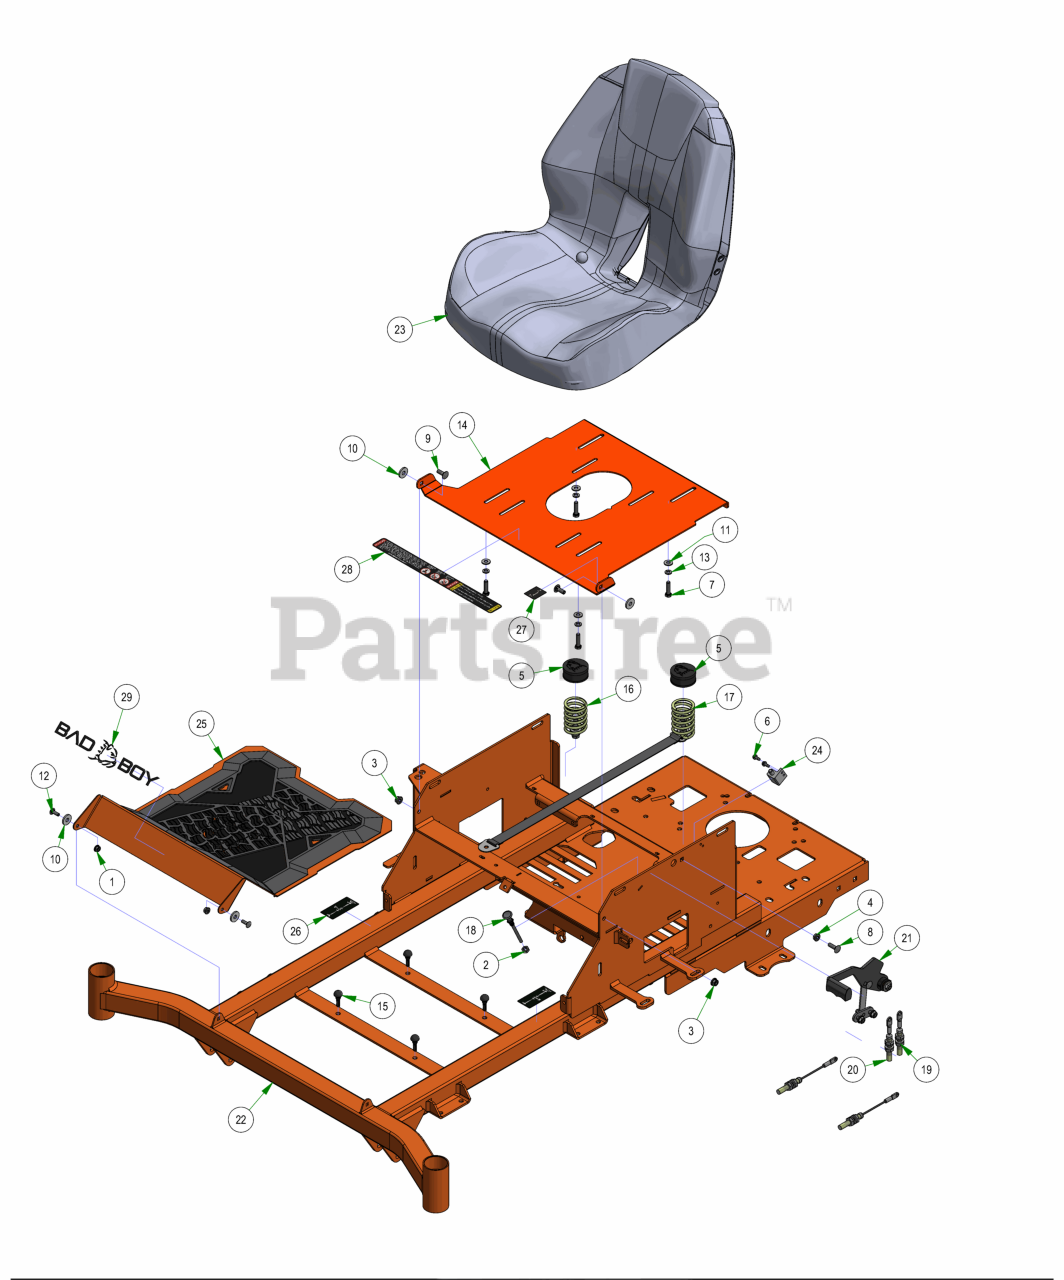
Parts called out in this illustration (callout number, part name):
1	1/4-20 NYL INSERT FLANGE LOCKNUT ZINC
2	3/8-24 HEX NUT ZINC YELLOW
3	5/16-18 NYLON INSERT FLANGE LOCKNUT ZINC
4	5/16-18 HEX SERRATED FLANGE NUT HARD/ZINC
5	Spring Cap Cover
6	12-24 X 1/2 HEX WASHER UNLSOT F TCS ZINC
7	5/16-18 X 1-1/4 HEX C/S (GR.5) ZC
8	5/16-18 X 1 CARRIAGE BOLT (GR.8) ZINC
9	5/16-18 X 7/8 CARRIAGE BOLT ZINC
10	.360 ID X .983 OD X .120 THICK FLAT WASHER NYLON
11	1/4 USS FLAT WASHER (3/4 OD) ZINC
12	1/4-20 X 3/4 CARRIAGE BOLT (GR.5) ZINC
13	5/16 SPLIT LOCKWASHER ZINC
14	2022 Avenger Seat Plate
15	2023 Floor Board Rubber Bumper
16	Seat Spring Assembly
17	2022 Mav/HD seat spring assembly with strap
19	2021 Load Balanced Brake Cable 1
20	2021 Load Balanced Brake Cable 2
21	2021 Load Balanced Brake Handle Assembly
22	2025 MZ-Avenger 54-60 Frame
23	2025 Avenger Seat
24	Safety Switch
25	2025 MZ/Avenger Floorboard Assembly
26	2018 LH/RH Steering Control Decal Roll
27	2018 MZ/Magnum/ZT/MAV/Comp Out Brake Decal
28	Outlaw Warning Decal
29	Flying Bulldog Front Bumper Decal
